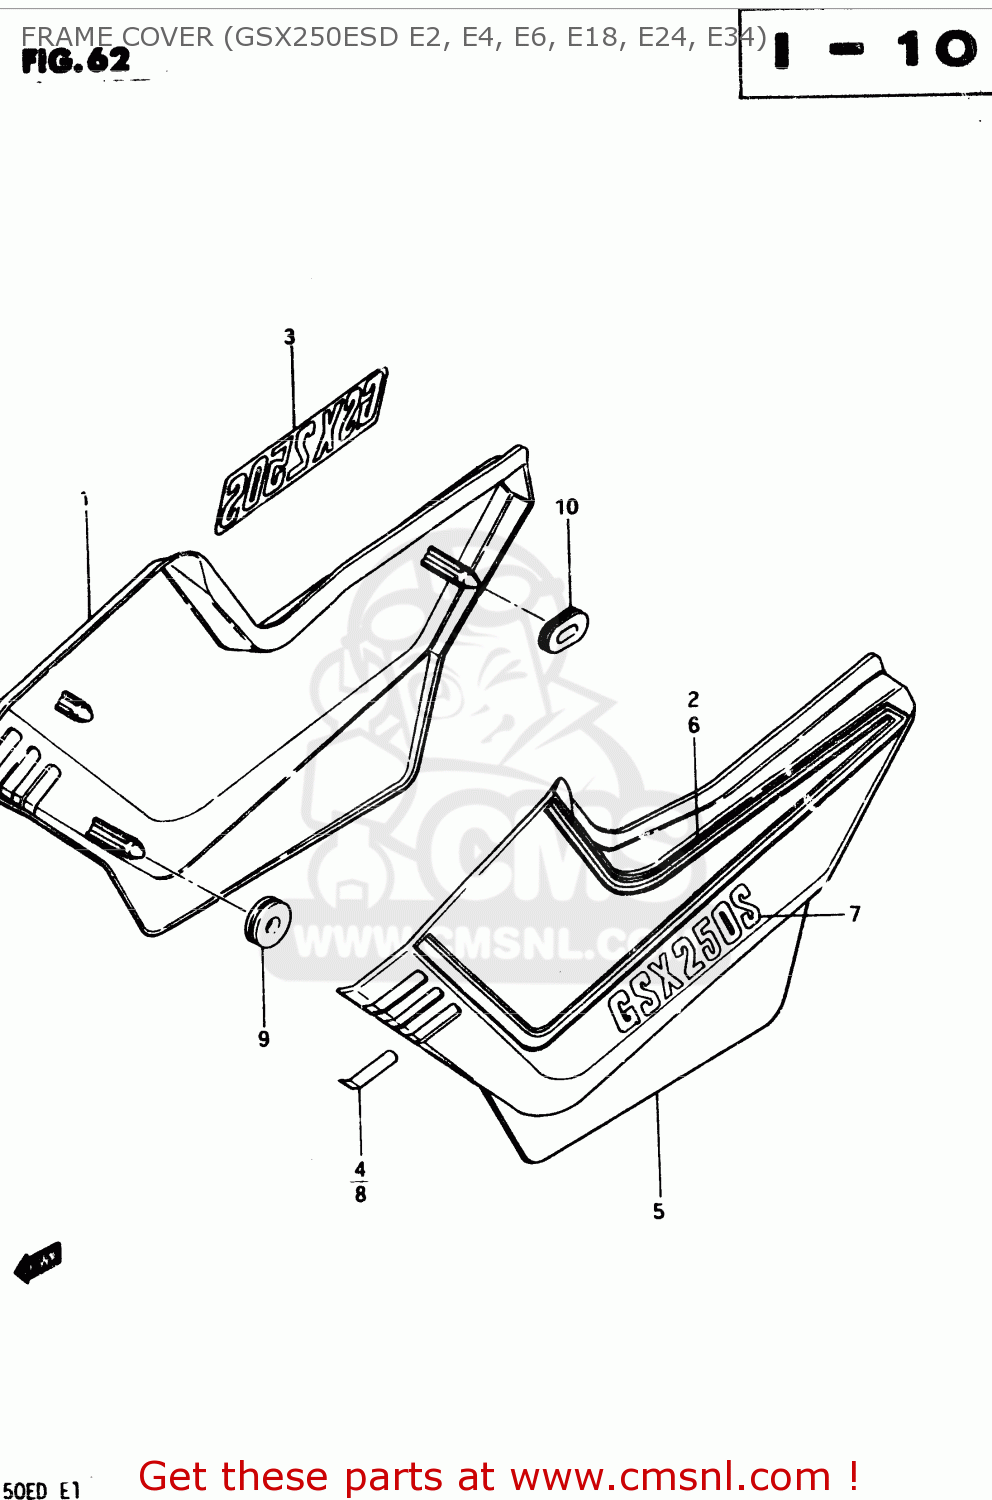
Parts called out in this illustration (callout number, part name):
1	COVER, FRAME RH
2	TAPE SET, FRAME COVER RH
3	EMBLEM, LH
4	LABEL,FRAME COVER DENT
5	COVER, FRAME LH (RED)
6	TAPE SET, FRAME COVER LH
7	EMBLEM, LH
8	LABEL,FRAME COVER
9	CUSHION
10	CUSHION
